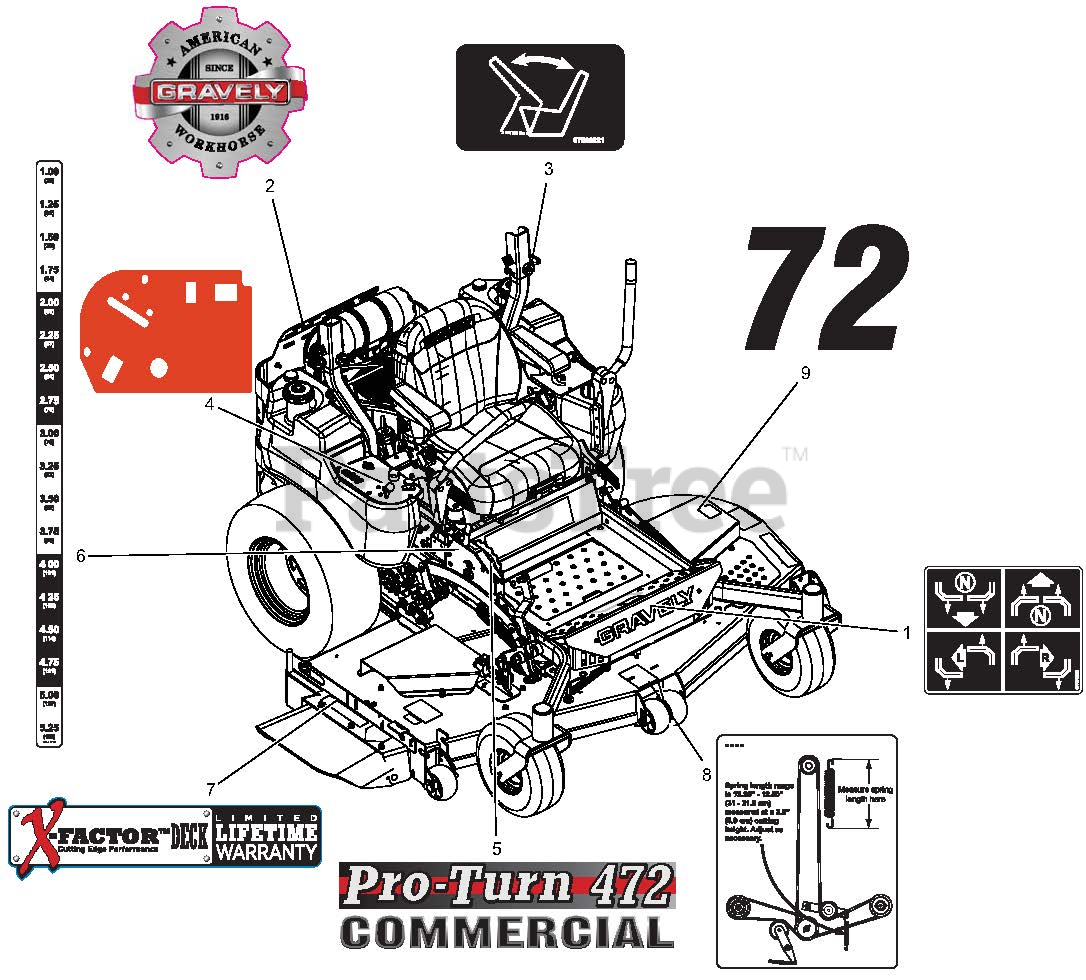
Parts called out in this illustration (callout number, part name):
1	DECAL, INSTRUCTIONAL - STEERING
2	DECAL, GRAVELY HERITAGE-LARGE
3	DECAL, SEAT RELEASE
4	DECAL, EFI CONTROL PANEL
5	DECAL, PRO-TURN 472 COMMERCIAL
6	DECAL, PT400 HEIGHT OF CUT
7	DECAL, X-FACTOR DECK
8	DECAL, BELT DIAGRAM
9	DECAL, 72"
